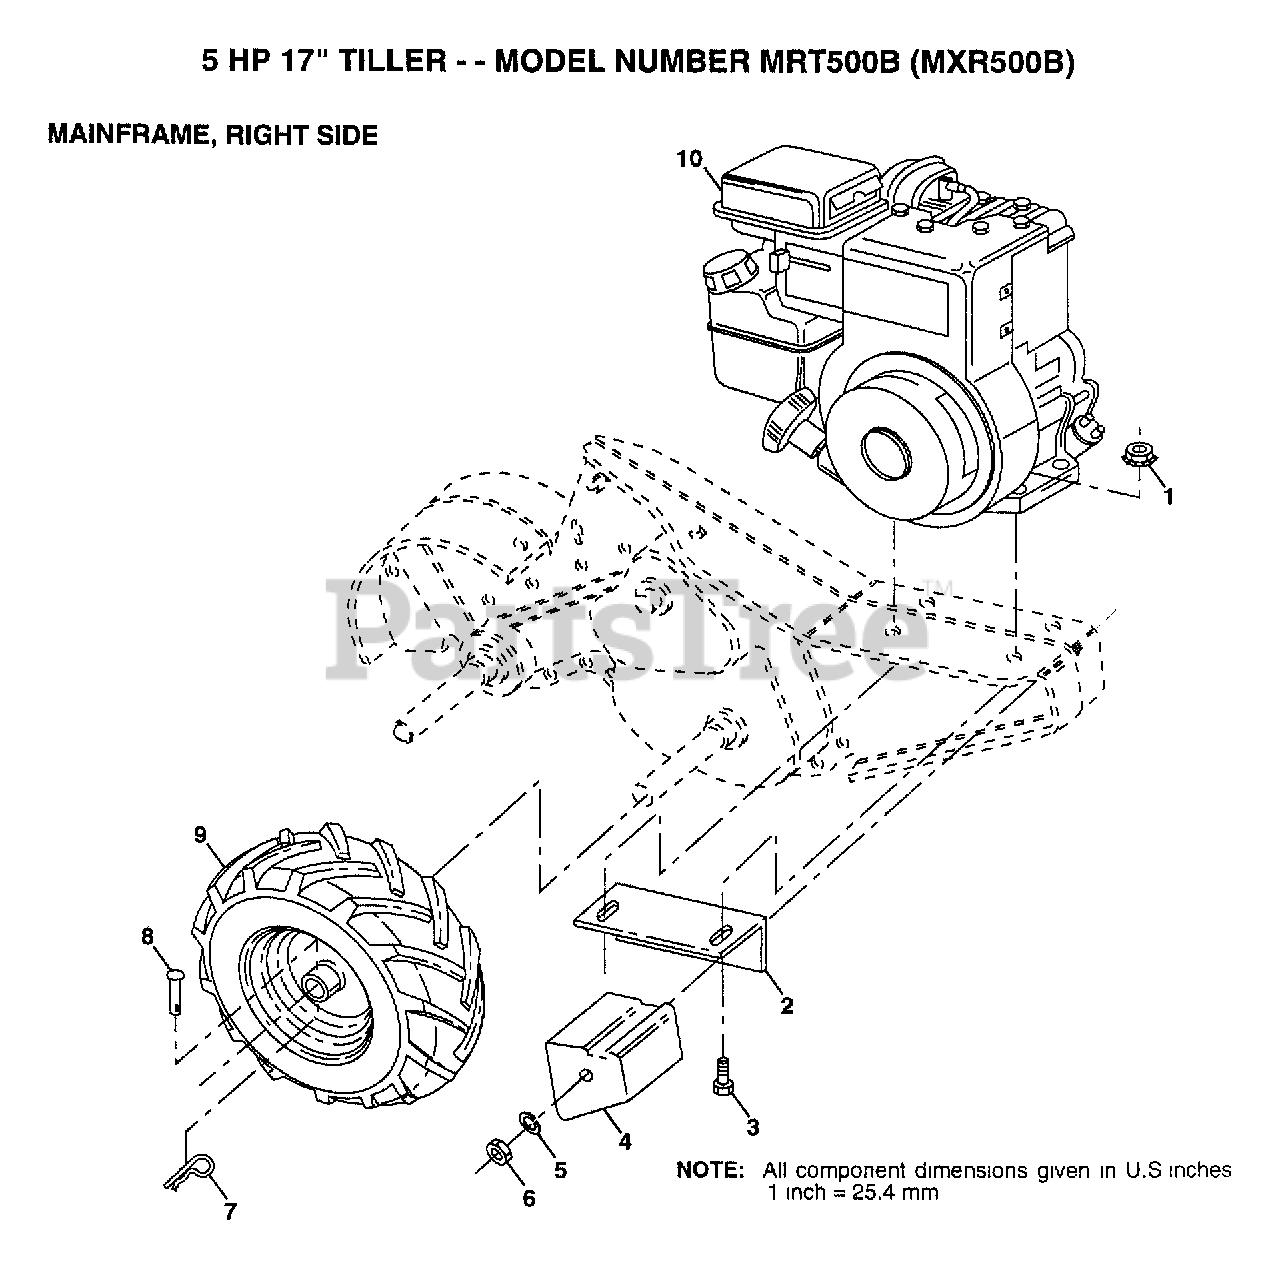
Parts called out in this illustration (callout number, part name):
2	BRACKET RH CRT
3	BOLT.HEX.5/16-1.5
4	COUNTERWEIGHT CRT
5	LOCKWASHER
6	NUT.HEX.3/8-16UNC
7	RETAINER M
8	RIVET.DRILL.1.75
9	TIRE.CHV.13X5.0-6
